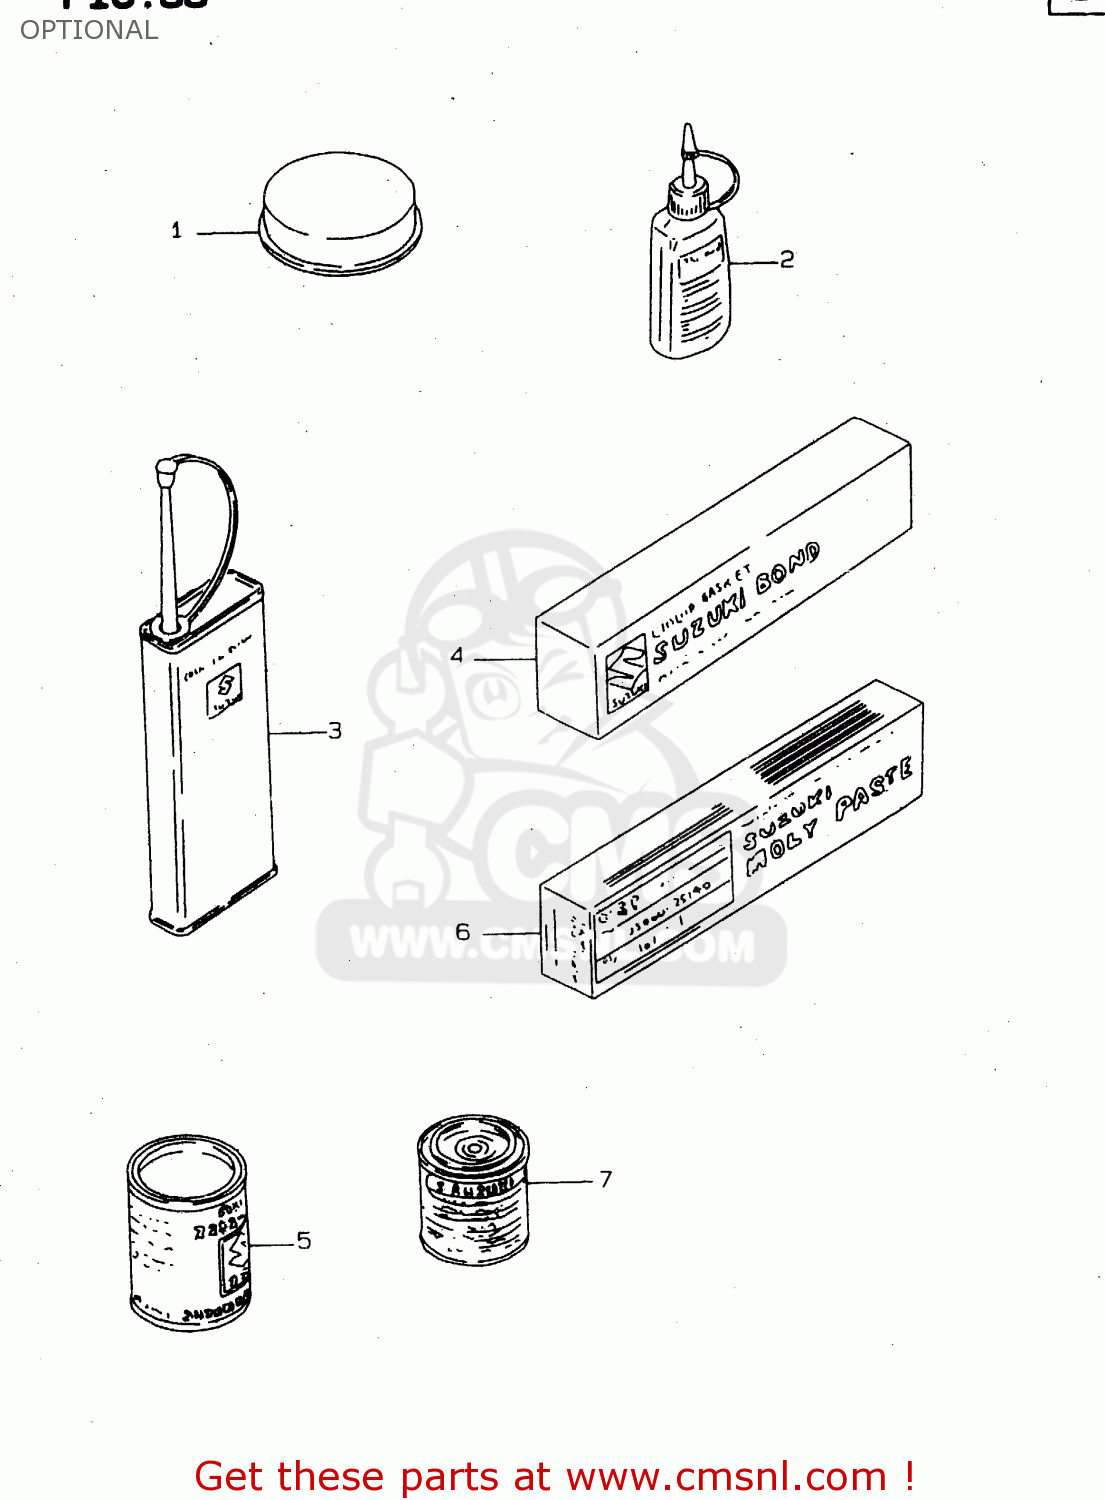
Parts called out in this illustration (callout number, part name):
1	GREASE,PBC FOR BRK PAD 20G
2	THREAD LOCK NO.1342
3	THREAD LOCK NO.1401 CLEAR 200G
4	LIQUID GSKT NO.1215 250G
5	GREASE(C)EP2 LITHIUM 150G
6	SUZUKI MOLY PASTE
7	PAINT,BLACK
